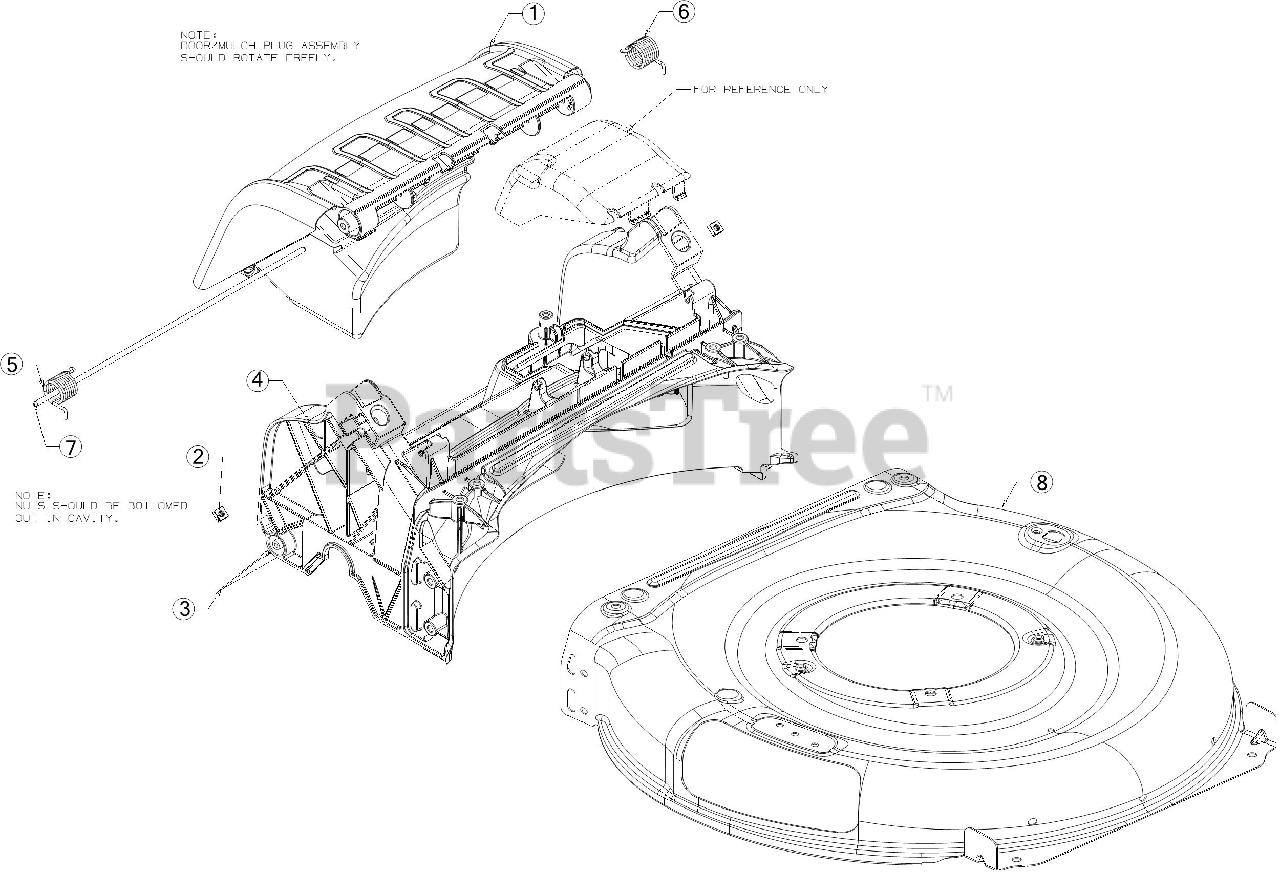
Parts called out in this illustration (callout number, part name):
1	REAR DOOR ASSEMBLY
2	SQUARE NUT 1/4-20
3	TRAILSHIELD
4	REAR BAFFLE
5	TORSION SPRING (RH)
6	TORSION SPRING (LH)
7	REAR DOOR PIVOT ROD
8	21" DECK (3N1)
